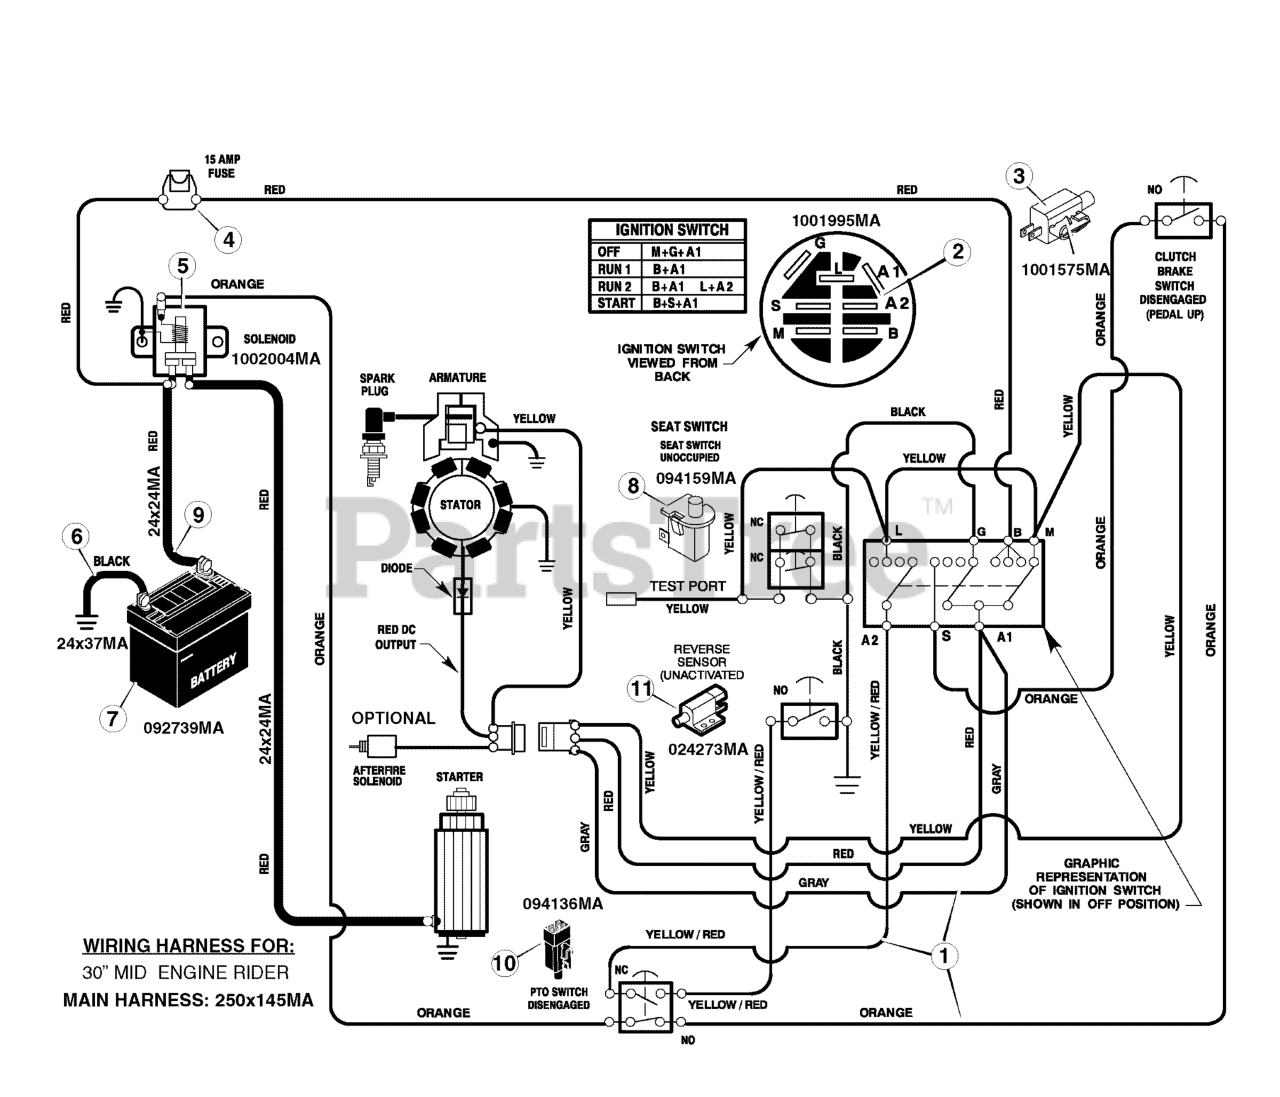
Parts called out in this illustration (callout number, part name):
1	Harness, Chassis Wire
2	Switch, Ignition
3	Switch, Limit
5	Solenoid
6	Cable, Battery Ground
7	Battery
8	Switch, Seat Sensor
9	Cable, Red Batery
10	Switch, Limit PTO
11	Switch, Limit Reverse
